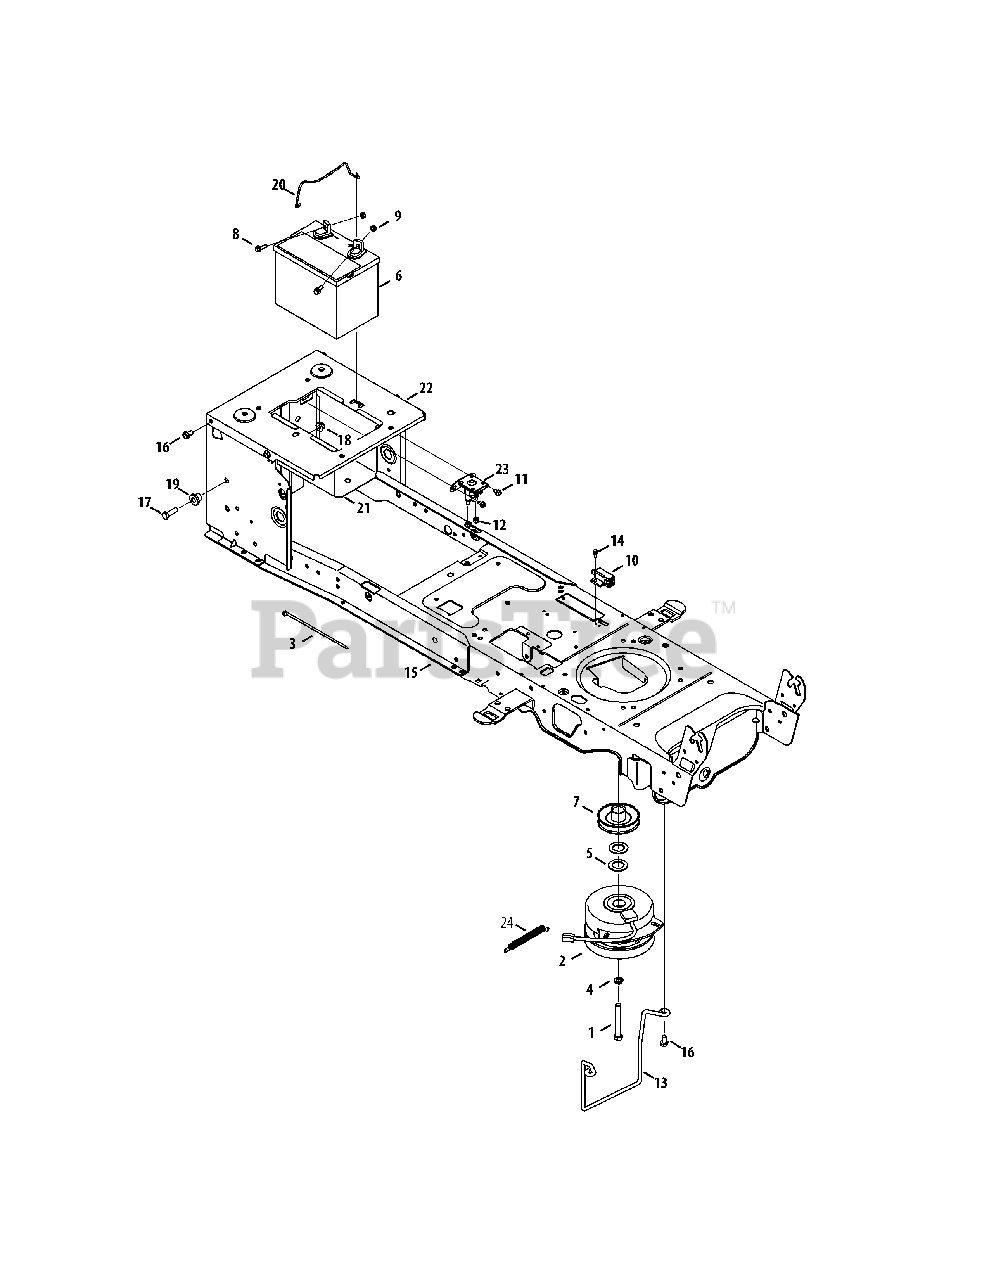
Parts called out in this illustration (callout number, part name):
1	Hex Screw, 7/16-20, 3.50, Gr5, Lock
2	Clutch, Electric PTO
3	Cable, Tie, 3/16 X .05 X 7.4
4	Washer, Lock, 7/16 , Regular Duty
5	Washer, Flat, 1.031 X1.620 X.095
7	Engine Pulley, Electric PTO
8	Hex Flange Screw, 1/4-20, .75, Gr5
9	Nut, Sems, 1/4-20
10	Switch, Interlock
11	Screw, Self-tapping, 1/4-20, 0.375
12	Nut, Flange Lock, 1/4-20, Nylon
13	Rod, Keeper (46")
13	Rod, Keeper (50")
14	Screw, Shoulder, #10-32, .50
15	Frame Assembly, Lower
16	Screw, Self-tapping, 5/16-18, .750
17	Hex Screw, 3/8-16, 1.25, Gr5, Std
18	Nut, Flange Lock, 3/8-16, Nylon
19	Spacer, Shoulder, .38 X 1.0 X .70
20	Rod, Battery
21	Tray, Battery
22	Bracket, Frame, Seat
23	Solenoid, 12V, 100 Amp, 4 term
24	Spring, Extn, .56 Dia X 5.52
